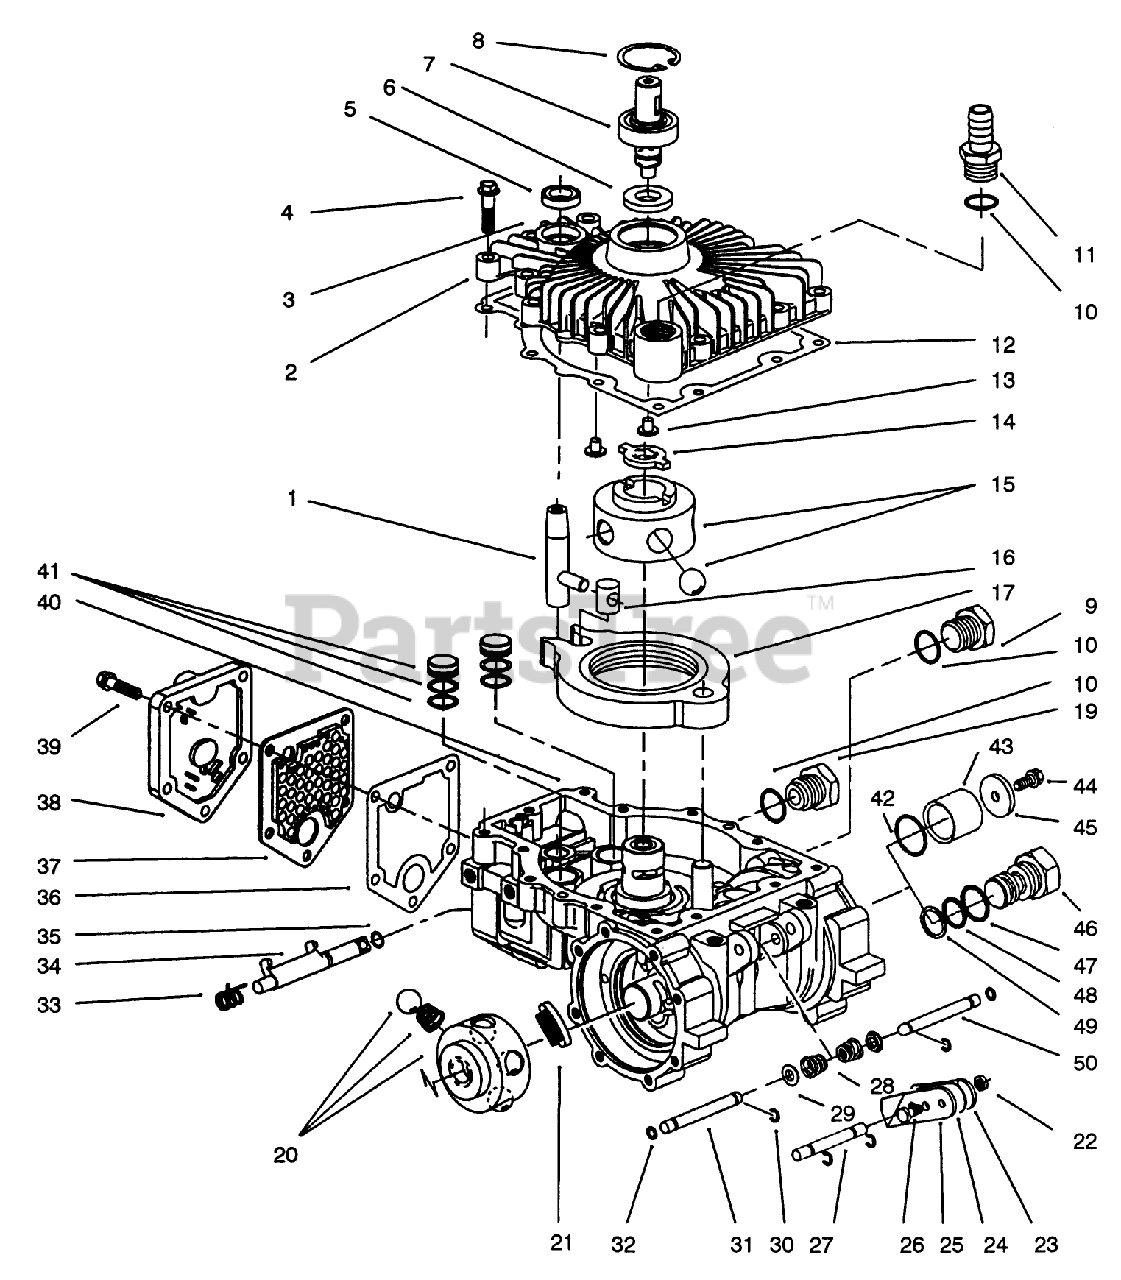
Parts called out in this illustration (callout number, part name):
1	CONTROL SHAFT
2	COVER ASM
3	COVER
5	SEAL-OIL
10	O-RING
17	CAM RING ASM
19	ROTOR BALL ASM
20	ROTOR BALL ASM
25	LH BRAKE LEVER
26	HEX HEAD SCREW
27	BRAKE SHAFT
31	PUSH ROD
32	QUAD SEAL
34	DUMP VALVE BRACKET
39	1/4-20 HEX HEAD SCREW
41	PISTON ASM
42	O-RING
43	CUP SEAL
45	WASHER
47	O-RING
48	O-RING
49	BACKUP RING
50	PUSH ROD
